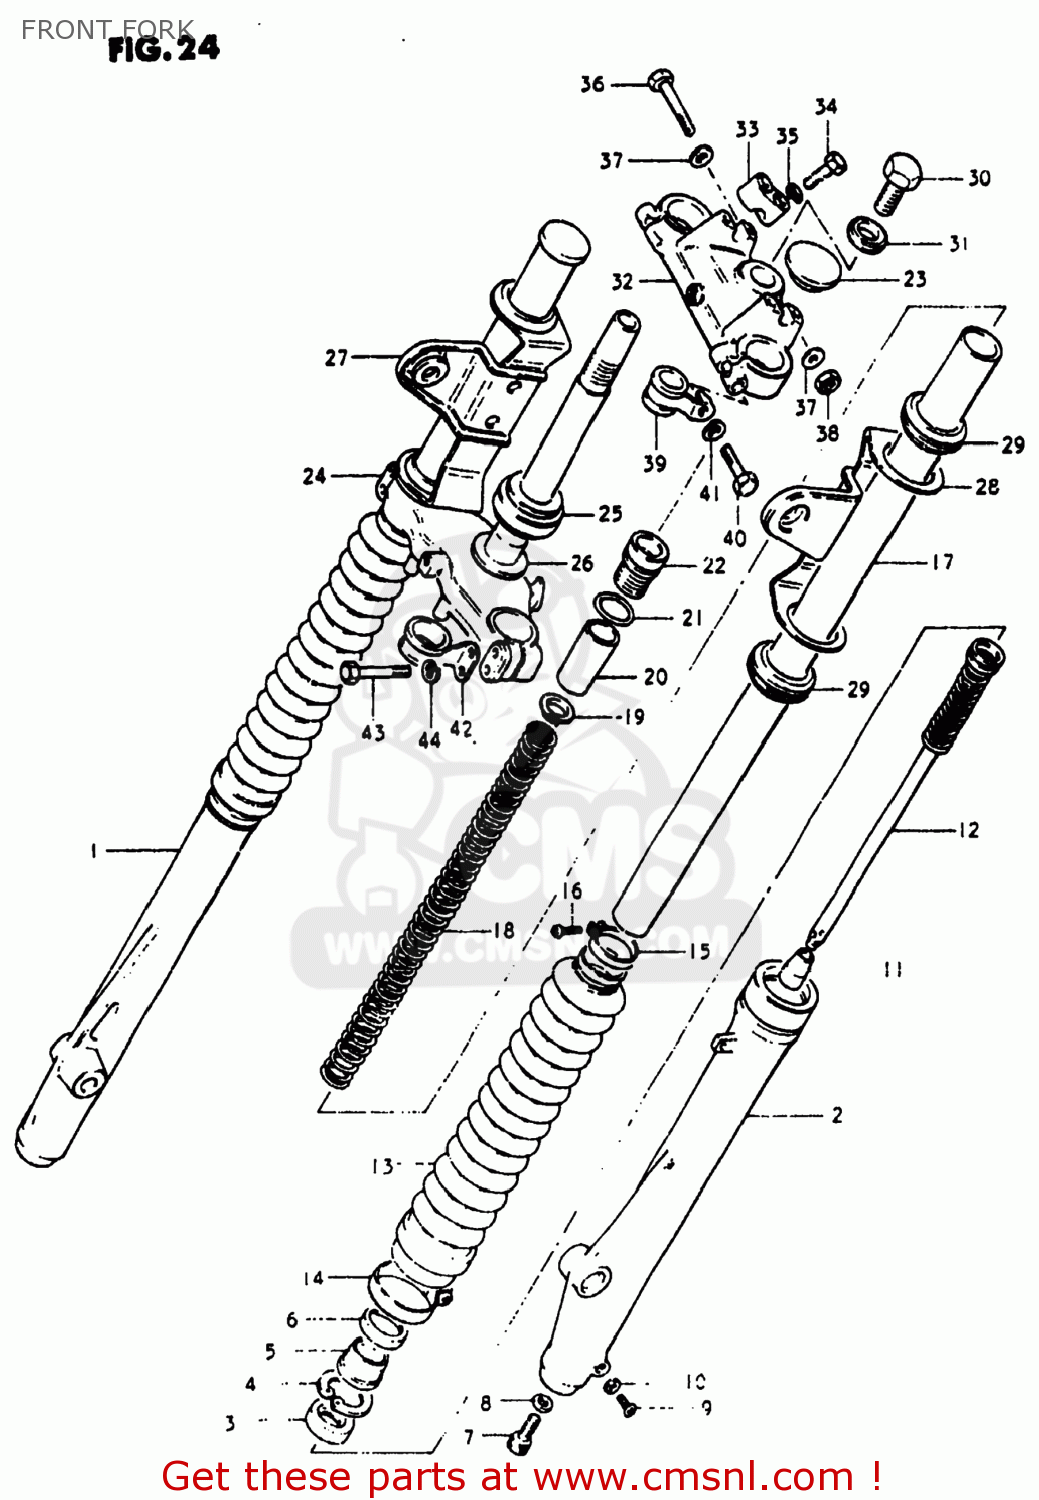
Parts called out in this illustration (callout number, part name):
0	DAMPER SET
1	TUBE,OUTER,RIGHT
2	TUBE,OUTER,LEFT
3	OIL SEAL,FRONT FORK
4	5
5	SEAL,DUST
6	CASE,DUST SEAL
7	BOLT,FORK CYLINDER(10X25)
8	GASKET (NAS)
9	SCREW
10	GASKET,DRAIN,PLUG (NAS)
11	PIECE,OIL LOCK
12	CYLINDER,FRONT FORK
13	BOOT
14	BAND,FRONT FORK COVER
15	BAND,BOOT
16	SCREW
17	TUBE,FORK,INNER
18	SPRING
19	GUIDE,FRONT FORK SPRING C
20	SPACER,SPRING
21	O RING
22	CAP,FORK INNER TUBE
23	CAP,FRONT FORK
24	STEM,STEERING
25	BEARING
26	WASHER,THRUST
27	BRACKET,HEADLAMP,RIGHT
28	BRACKET,HEADLAMP,LEFT
29	CUSHION,HEADLAMP BRACKET
30	BOLT
31	WASHER
32	HEAD,STEERING STEM
33	HOLDER,HANDLEBAR
34	BOLT
35	LOCK WASHER
36	BOLT 8X50
37	WASHER
38	NUT
39	GUIDE,CABLE
40	BOLT
41	LOCK WASHER
42	CLIP,CABLE
43	BOLT 8X45
44	LOCK WASHER
